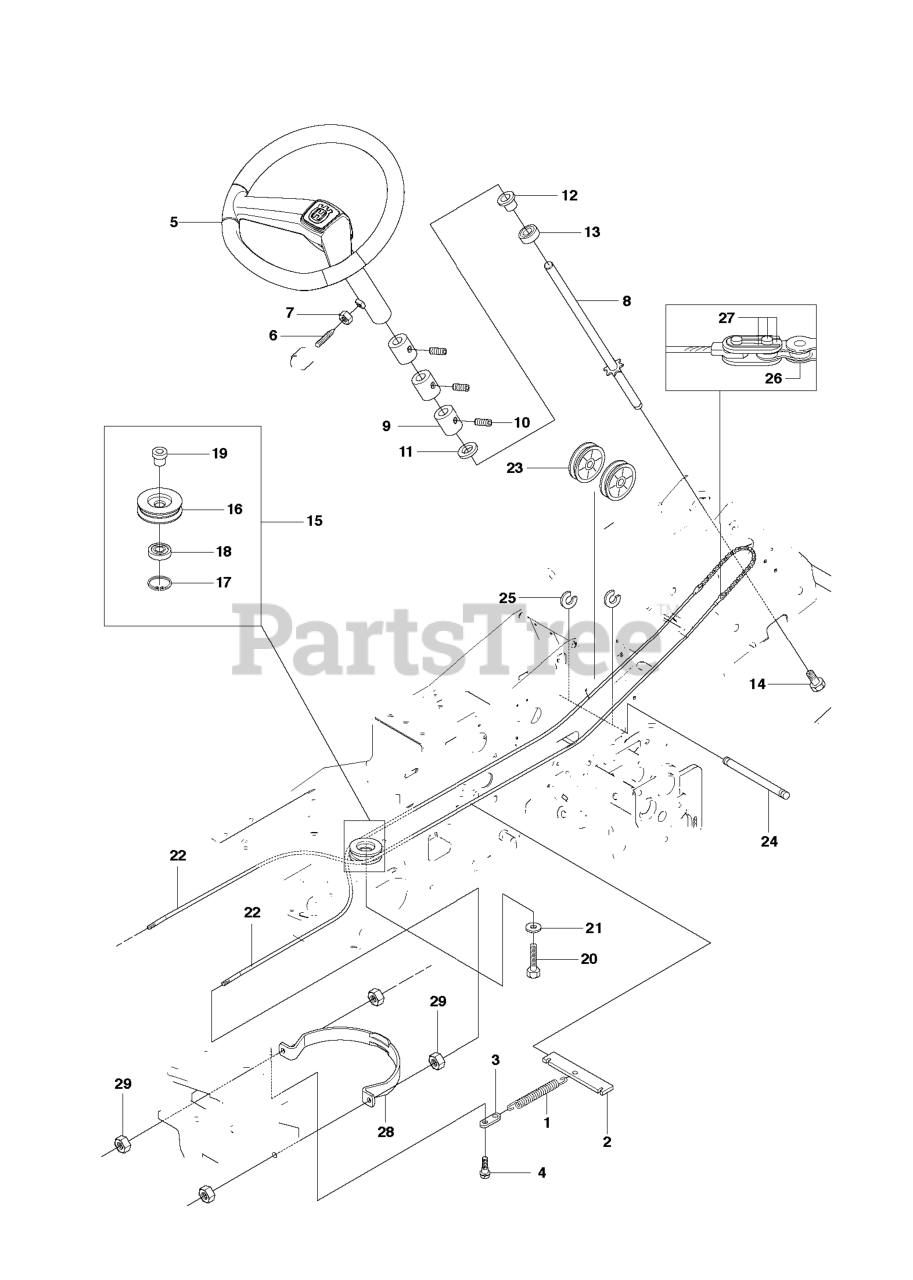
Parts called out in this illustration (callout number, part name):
2	SPRING BRACKET
5	STEERING WHEEL
7	NUT
8	STEERING ROD
9	SPACER
13	BALL BEARING 6004-2RS1
17	CIRCLIP SGH 47
18	BALL-BEARING 6204-2RS
22	RP STEERING CABLE COMPLETE
24	SHAFT
25	RETAINING RING
26	STEERING CHAIN
28	WIRE GUIDE
29	NUT
